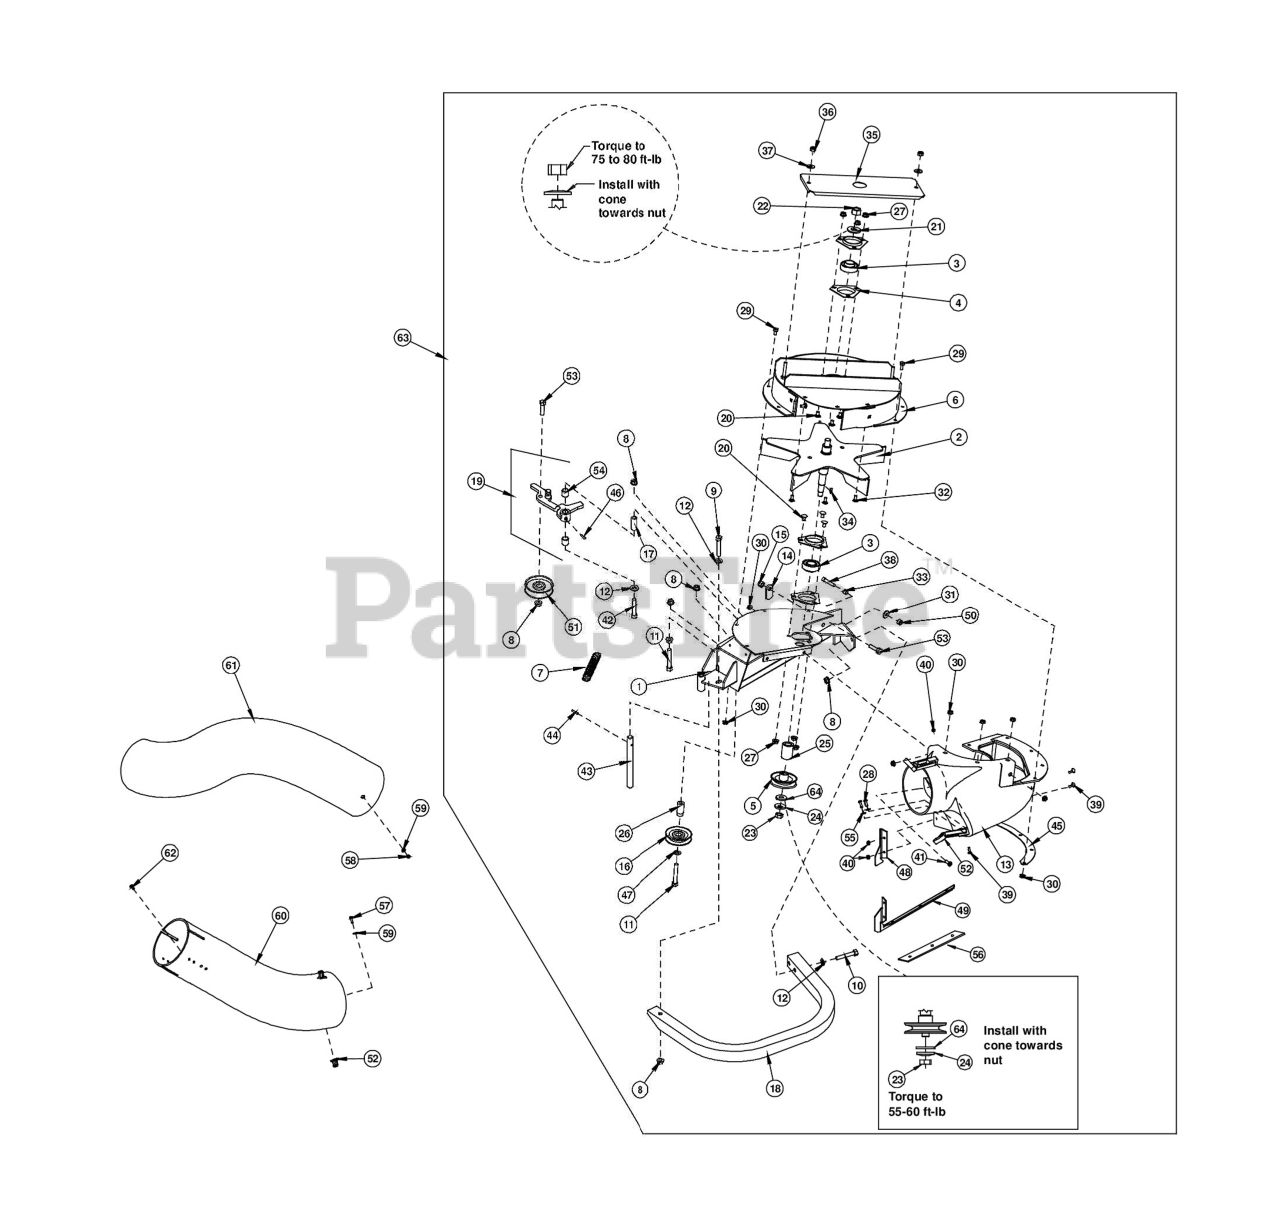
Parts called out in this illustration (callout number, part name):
1	WLD,BLOWER MOUNT
2	IMPELLER
3	BEARING
4	HOUSING-FLANGE
5	SHEAVE-BLOWER
6	ASM, UPPER HOUSING LZUV52
7	SPRING-IDLER
8	NUT-HHF, WHIZ
9	SCREW-HH
10	SCREW-HH
11	SCREW-HH
12	WASHER-FLAT
13	CHUTE-BLOWER, SMALL
14	LATCH-CATCHER, GRASS
15	NUT-LOCK, NI
16	IDLER-INSIDE
17	BUSHING-PIVOT, IDLER
19	ASM, IDLER ARM - SERVICE
20	SCREW-CARR
21	WASHER-SPRING
22	NUT-HEX
23	NUT-JAM
24	WASHER-SPRING
28	SCREW-PPH
29	SCREW-HH
31	WASHER-SPRING
32	SCREW-CARR
33	BUSHING, LOCATOR
34	KEY-WOODRUFF
35	ASM, BEARING COVER
36	NUT-LOCK, NI
37	WASHER-FLAT
38	SCREW-HSH
39	SCREW-HEAD, TRUSS
42	SCREW-HSBH
43	SHAFT-CATCHER, GRASS
44	PIN-ROLL
45	PLATE-BACKING, BLOWER
46	FITTING-GREASE
47	WASHER-FLAT
48	PLATE, FILLER
49	PLATE, BLOCKER
50	NUT-HEX
51	IDLER-FLAT
52	LATCH DRAW
53	SCREW-HH
54	BUSHING
55	WASHER-FLAT
56	PLATE-REINFORCEMENT
57	SCREW-PPH
58	NUT-LOCK, NI
59	WASHER-FLAT
60	KIT,LOWER TUBE
61	TUBE-UPPER
62	SCREW-HWH
63	ASM, BLOWER LZUV52 - SERV
64	WASHER-SPACER
